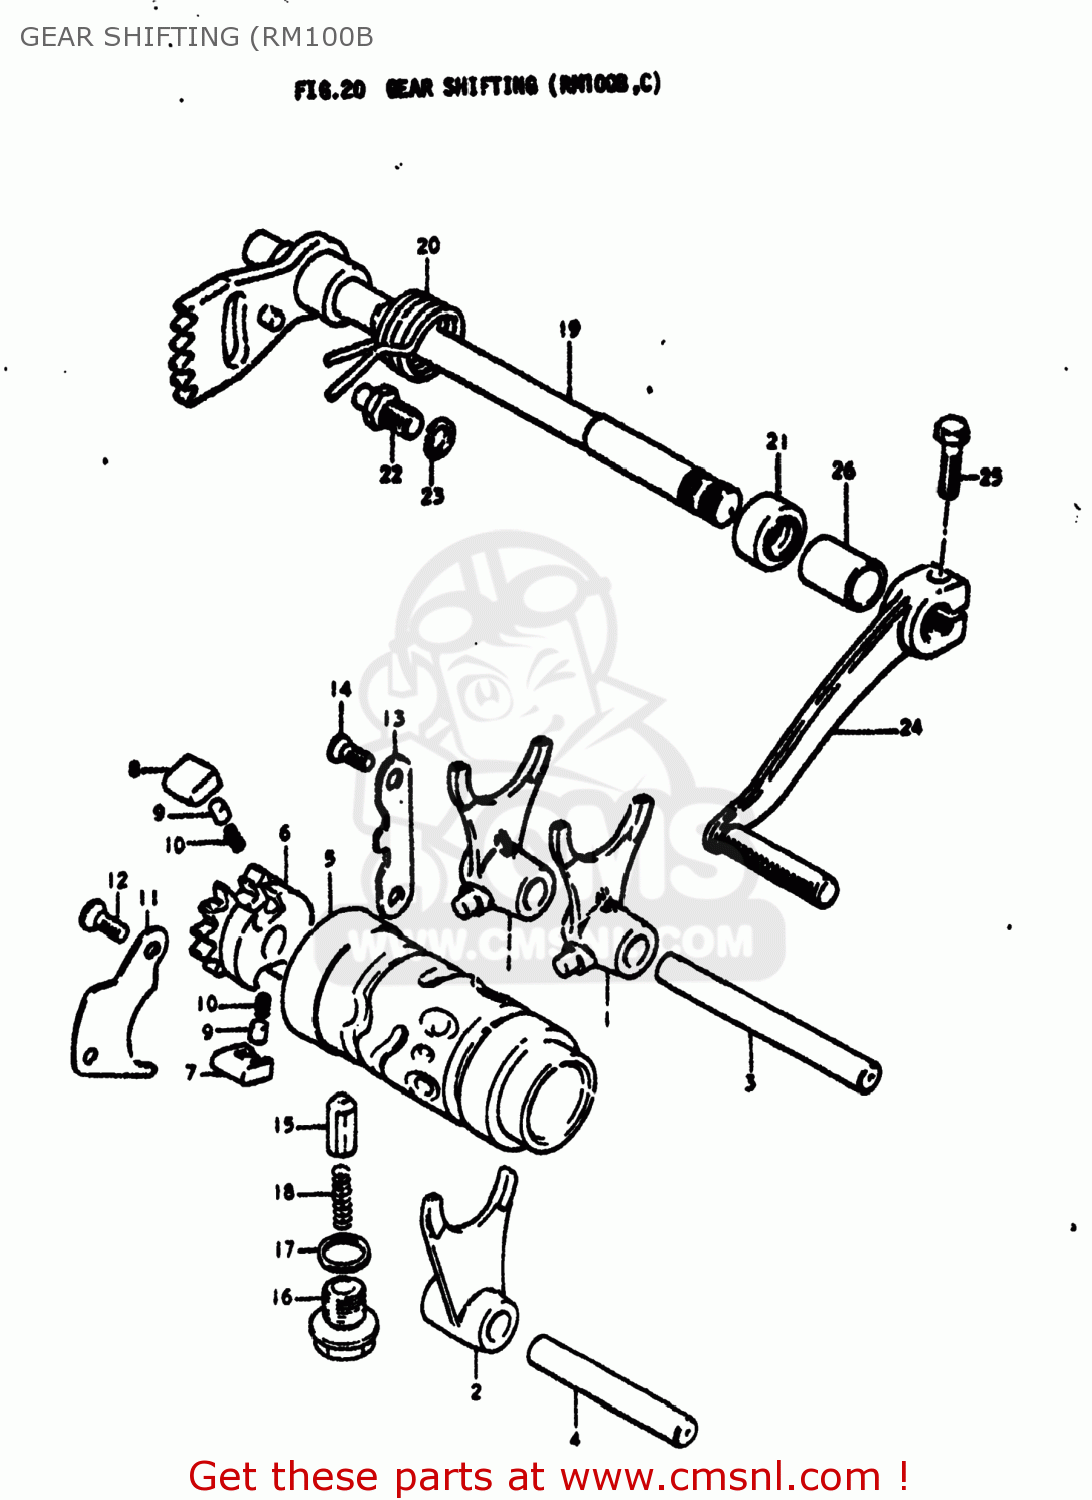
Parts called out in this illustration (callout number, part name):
1	FORK,GEAR SHIFT NO.1
2	FORK,GEAR SHIFT NO.2
3	SHAFT,GEAR SHIFT FORK
4	SHAFT,GEAR SHIFT FORK
5	CAM,GEAR SHIFT
6	RETAINER,GEAR SHIFT CAM
7	PAWL,GEAR SHIFT NO.1
8	PAWL,GEAR SHIFT NO.2
9	PIN(5X8)
10	SPRING
11	LIFTER,GEAR SHIFT PAWL
12	SCREW
13	STOPPER,GEAR SHIFT POLE
14	SCREW
15	STOPPER,GEAR SHIFTING
16	BOLT,GEAR SHAFT CAM STOPPER
17	GASKET 14.2X20.5X1.2 (NAS)
18	SPRING
19	SHAFT,GEAR SHIFT
20	SPRING
21	OIL SEAL
22	STOPPER,GEAR SHIFT CAM
23	LOCK WASHER
24	LEVER ASSEMBLY,GEAR SHIFTING
25	BOLT,M6X1X20
26	CUSHION
